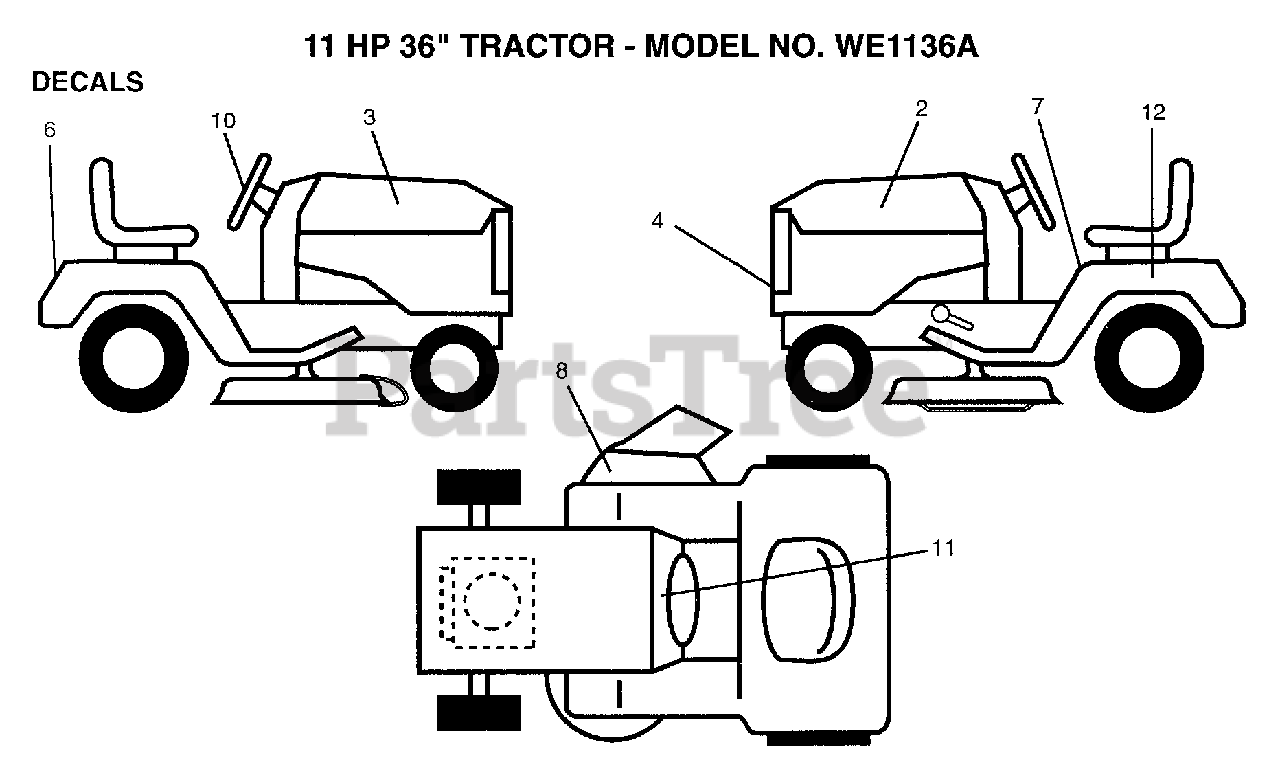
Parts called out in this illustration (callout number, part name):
2	DECAL.HOOD.LH
3	DECAL.HOOD.RH
4	DECAL.GRILL
6	DECAL.FENDER
7	DECAL
8	"DECAL, WARNING"
10	DECAL.WHL.STRG.
12	DECAL.FEND.QUICKS
